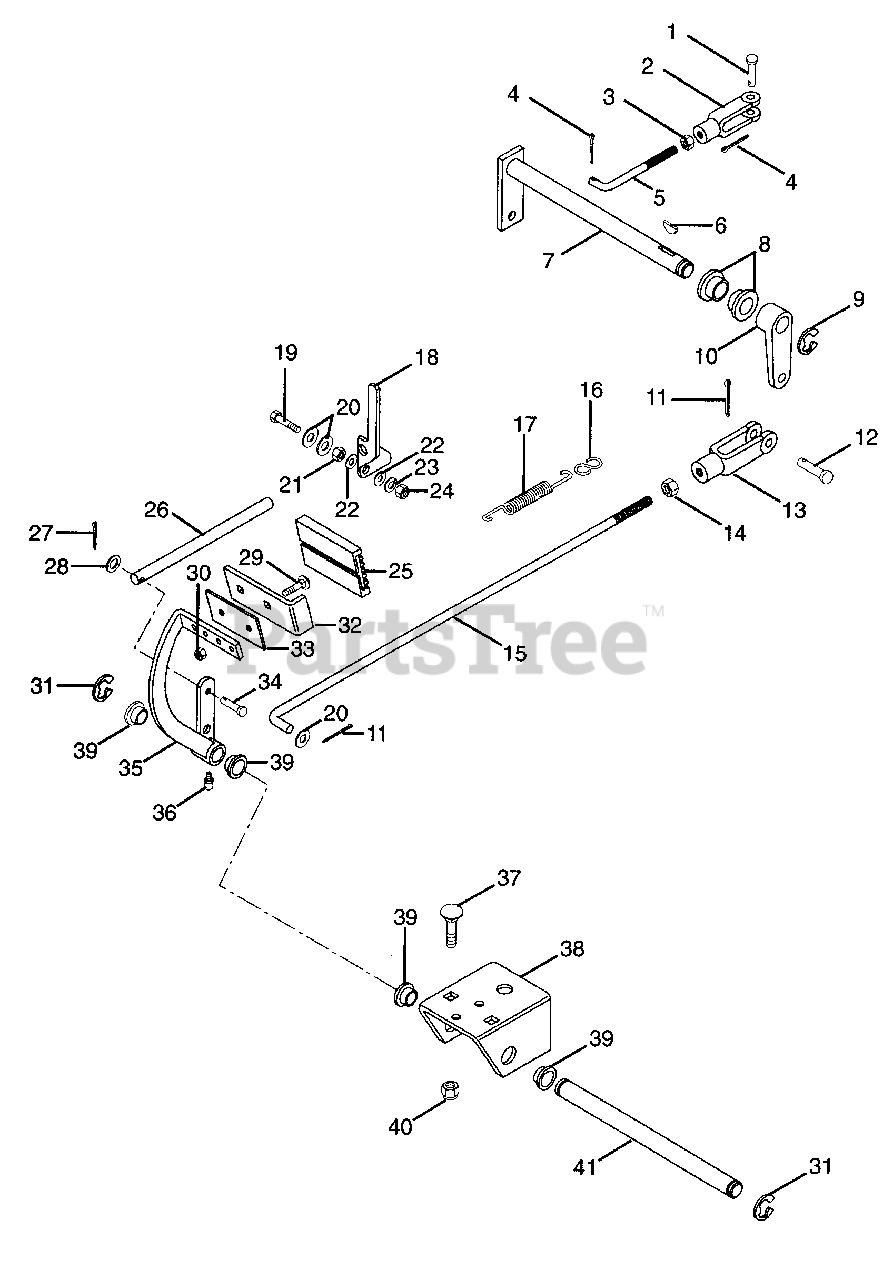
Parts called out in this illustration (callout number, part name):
1	Pin-Clevis .312 x .822
2	Yoke .31-24 x 2.250
3	Nut-Jam .312-24 Grade 2
4	Pin-Cotter .09 x .75
5	Rod-Parking Brake
6	Key-Woodruff .19 x .75
7	Weldment-Brake Cross Shaft
8	Bushing-Flange .762 x 1.0 x .580 x 1.48
9	Ring-Retaining-External .574 x .050
10	Lever-PTO
11	Pin-Cotter .12 x .75
12	Pin-Clevis .375 x .948
13	Clevis .38-24 Adjustable
14	Nut-Jam .375-24
15	Rod-Brake (Right Hand)
16	Clip-Spring
17	Spring-Tens .095 x .500 x 5.5
18	Arm-Parking Brake Lock
19	Bolt-Hex .38-16 x 1.25 Grade 5
20	Washer-Flat-Steel .406 x .812 x .065
21	Nut-Jam .375-16
22	Washer-Flat-Nylon .375 x .75 x .060
23	Washer-Lock .375 x .094
24	Nut-Locking-Center .375-16 Grade 2
25	Pad-Pedal
26	Rod
27	Pin-Cotter .062 x .75
28	Washer-Flat-Steel .281 x .62 x .065
29	Bolt-Round Head Square Neck .25-20 x 1.25
30	Nut-Locking-Center .250-20 Grade 2
31	Ring-Retaining-External .625 x .042
32	Pedal-Brake
33	Plate-Brake
34	Pin-Clevis .25 x 1.13
35	Weldment-Brake Pedal
36	Fitting-Lube .25-28 x .256
37	Bolt-Round Head Square Neck .38-16 x .75
38	Bracket-Brake Pedal
39	Bushing-Flange .630 x 1.000 x .625
40	Nut-Locking-Center .375-16 Grade 2
41	Shaft-Brake Pedal Mounting
